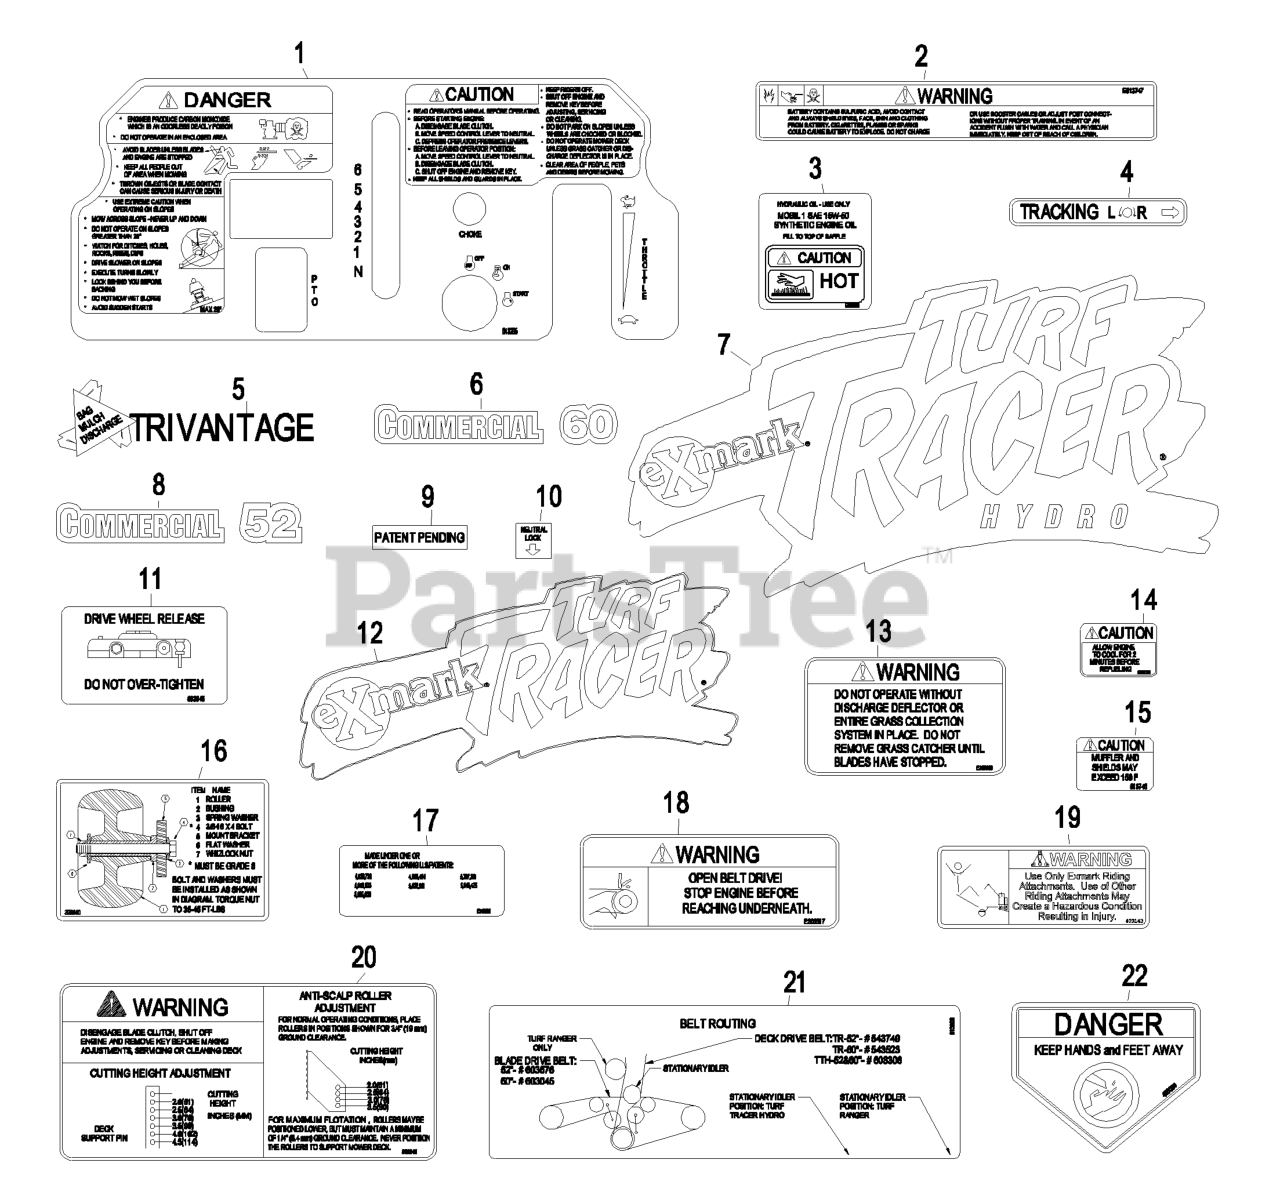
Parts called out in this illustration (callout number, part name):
2	DECAL-BATTERY
4	DECAL,TRACKING ADJUST
6	DECAL,COMMERCIAL 60
8	DECAL,COMMERCIAL 52
9	Decal, Patent Pending
10	DECAL,NEUTRAL LOCK
11	DECAL,DRIVE RELEASE
13	DECAL-WARNING, DISCHARGE
16	DECAL,ROLLER MOUNTING
18	DECAL,BELT DRIVE
19	DECAL,SULKY WARNING
20	DECAL,ANTI SCALP
21	DECAL,BELT ROUTING
22	DECAL-DANGER
